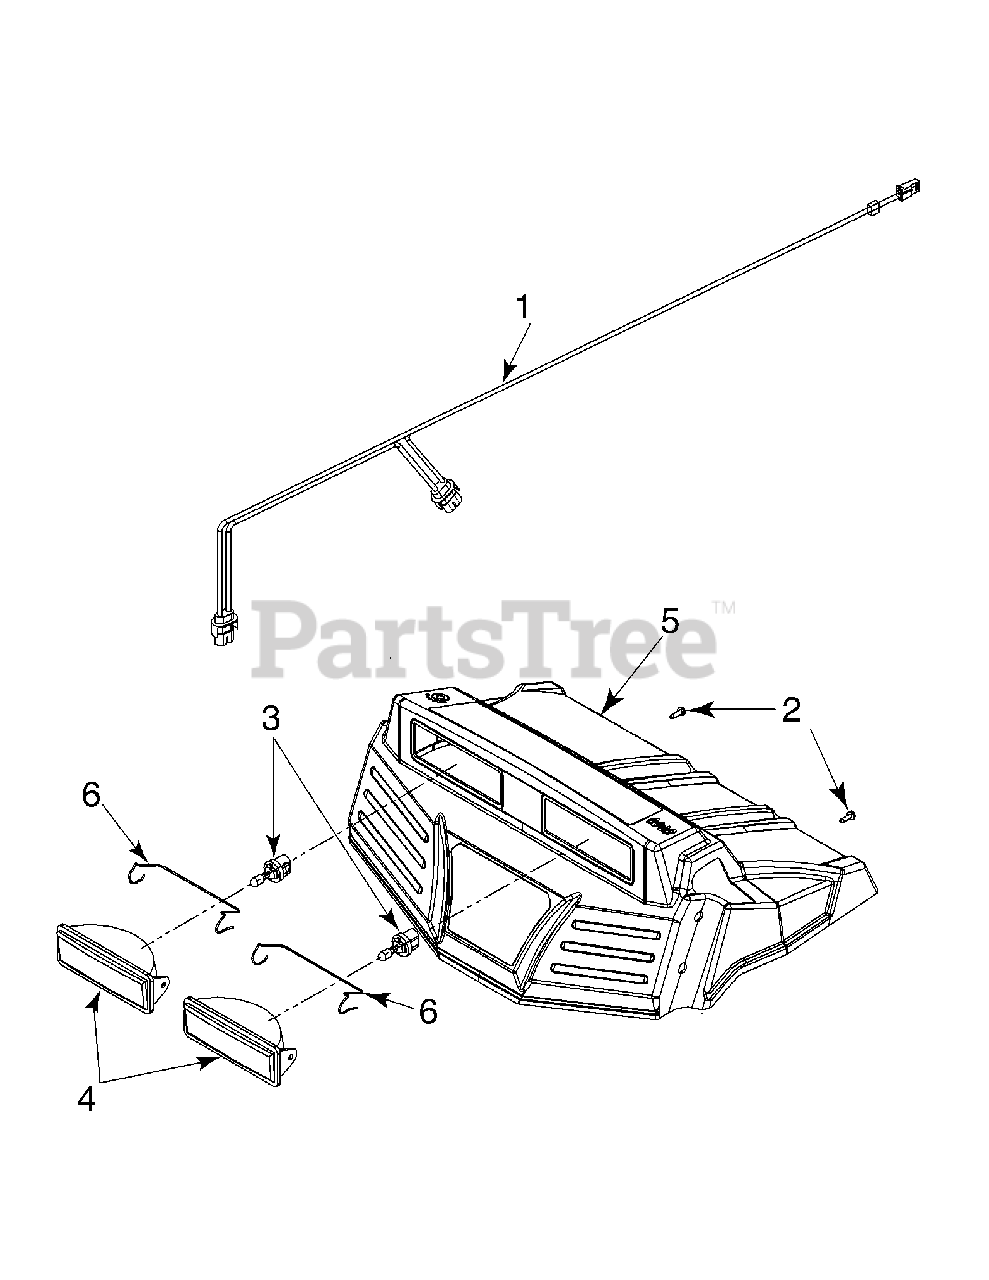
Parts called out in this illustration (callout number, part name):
1	Wire Harness
2	Hex Tapp Wash Hd. Scr. #10 x 5/8
3	Bulb #890, 12 V, 27 Watt
4	Head light Housing
5	Black Handle Panel
6	Retainer
